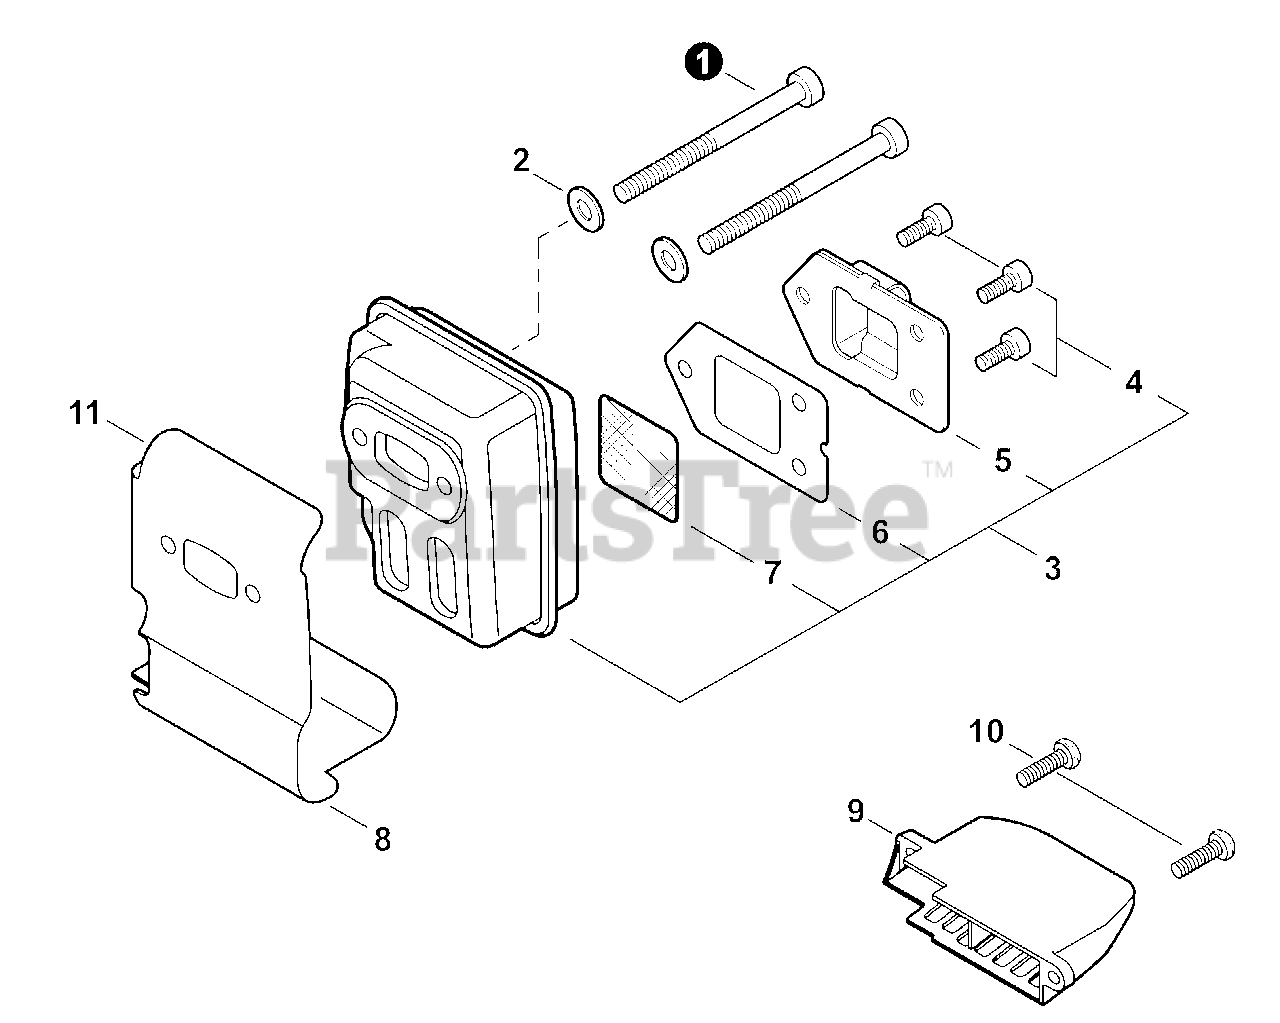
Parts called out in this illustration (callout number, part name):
1	BOLT, TORX 5×55
2	WASHER, FLAT 5.5×10×0.8
3	MUFFLER ASSY
4	BOLT, TORX 4×8
5	GUIDE, EXHAUST
6	GASKET, EXHAUST
7	SCREEN, SPARK ARRESTER
8	HEAT SHIELD, EXHAUST
9	COVER, MUFFLER
10	BOLT, TORX 5×16
11	GASKET KIT: ENGINE, INTAKE, EXHAUST
